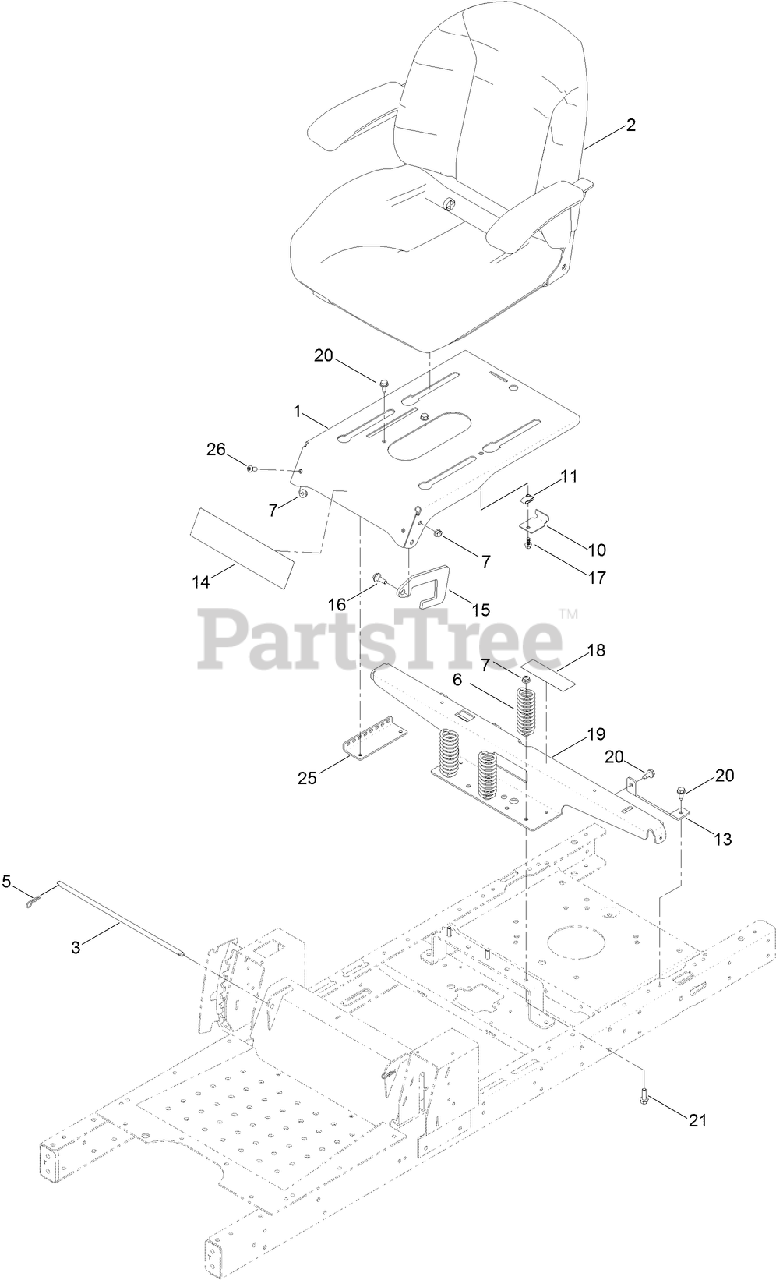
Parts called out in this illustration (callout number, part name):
2	SEAT ASM
3	ROD-PIVOT, NARROW
5	PIN-COTTER
6	SPRING-COMPRESSION
7	NUT-HF, NI
10	BRACKET-STOP, SEAT
13	SUPPORT-TANK, REAR
14	DECAL-TIMECUTTER
15	PLATE-STOP
16	SCREW-SHOULDER
17	SCREW-HHF
18	DECAL-SERVICE, CE
19	SUPPORT-POD
20	SCREW-HWHTF
21	SCREW-HHF
25	BRACKET-LATCH, SEAT
26	SCREW-HSBH
